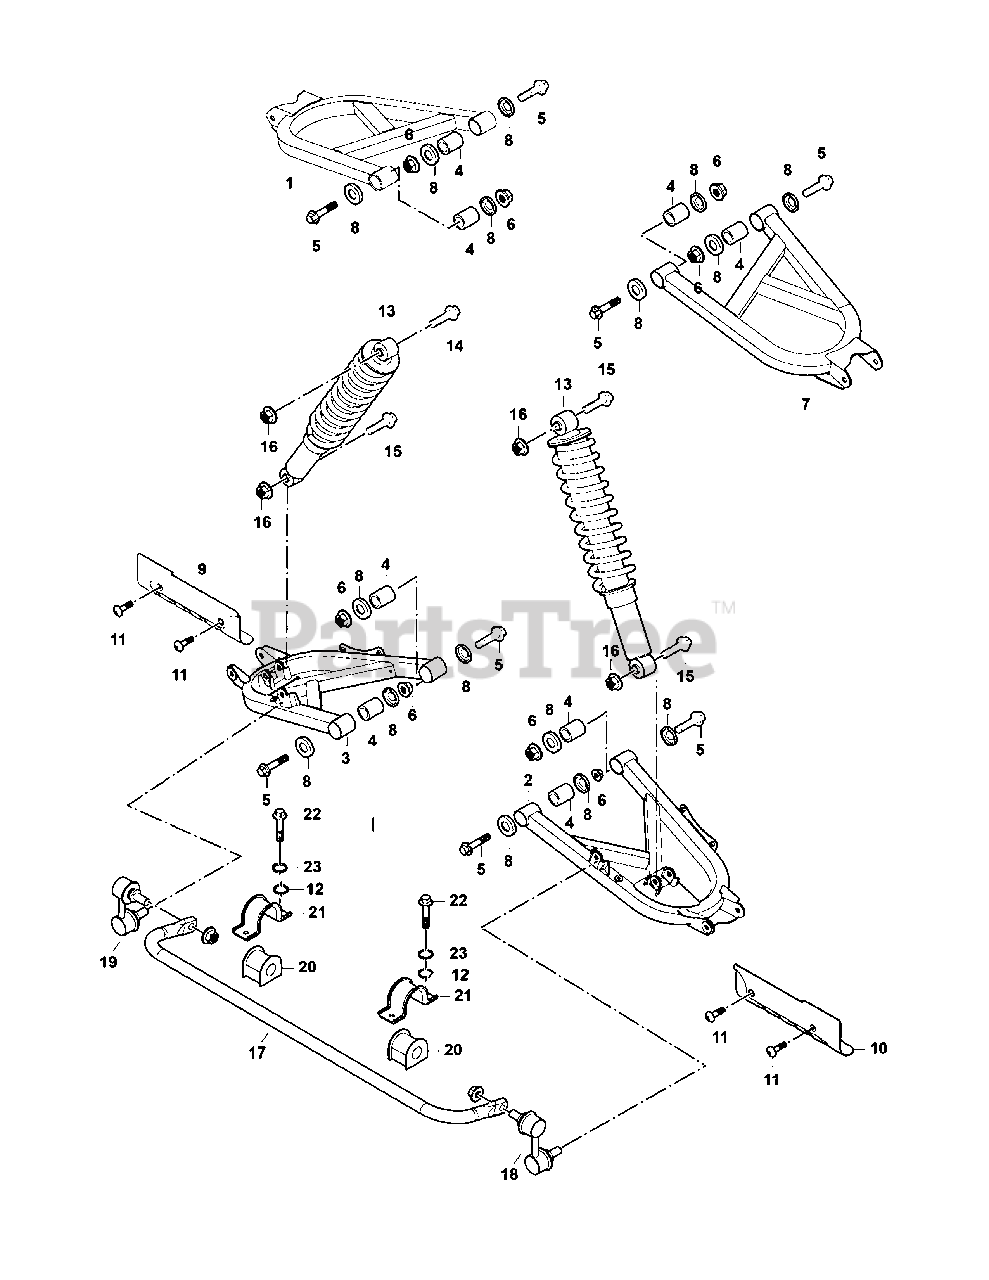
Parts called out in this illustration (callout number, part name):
1	Rear Right Upper Swing Arm
2	Rear Left Lower Swing Arm
3	Rear Right Lower Swing Arm
4	Bushing 10×23×50
5	Bolt M10×1.25×78
6	Hexagon flange nut M10×1.25
7	Rear Left Upper Swing Arm
8	Nylon Bushing
9	Protective Board, Rear Right Lower Swing Arm
10	Protective Board, Rear Left Lower Swing Arm
11	Cross large plate head screw M6×16
12	Cushion 8.4×16×1.6
13	Rear Shock Absorber
14	Hexagon Flange Bolt M12×1.25×70
15	Bolt M12×1.25×60
16	Hexagon Flange Nut M12×1.25
17	Rear Anti-Roll Bar
18	Left Tie-Rod, Anti-Roll Bar
19	Right Tie-Rod, Anti-Roll Bar
20	U-type Rubber bush III
21	Press Block, Rear Anti-Roll Bar
22	Hexagon Flange Bolt M8×22
23	Spring Washer -8
